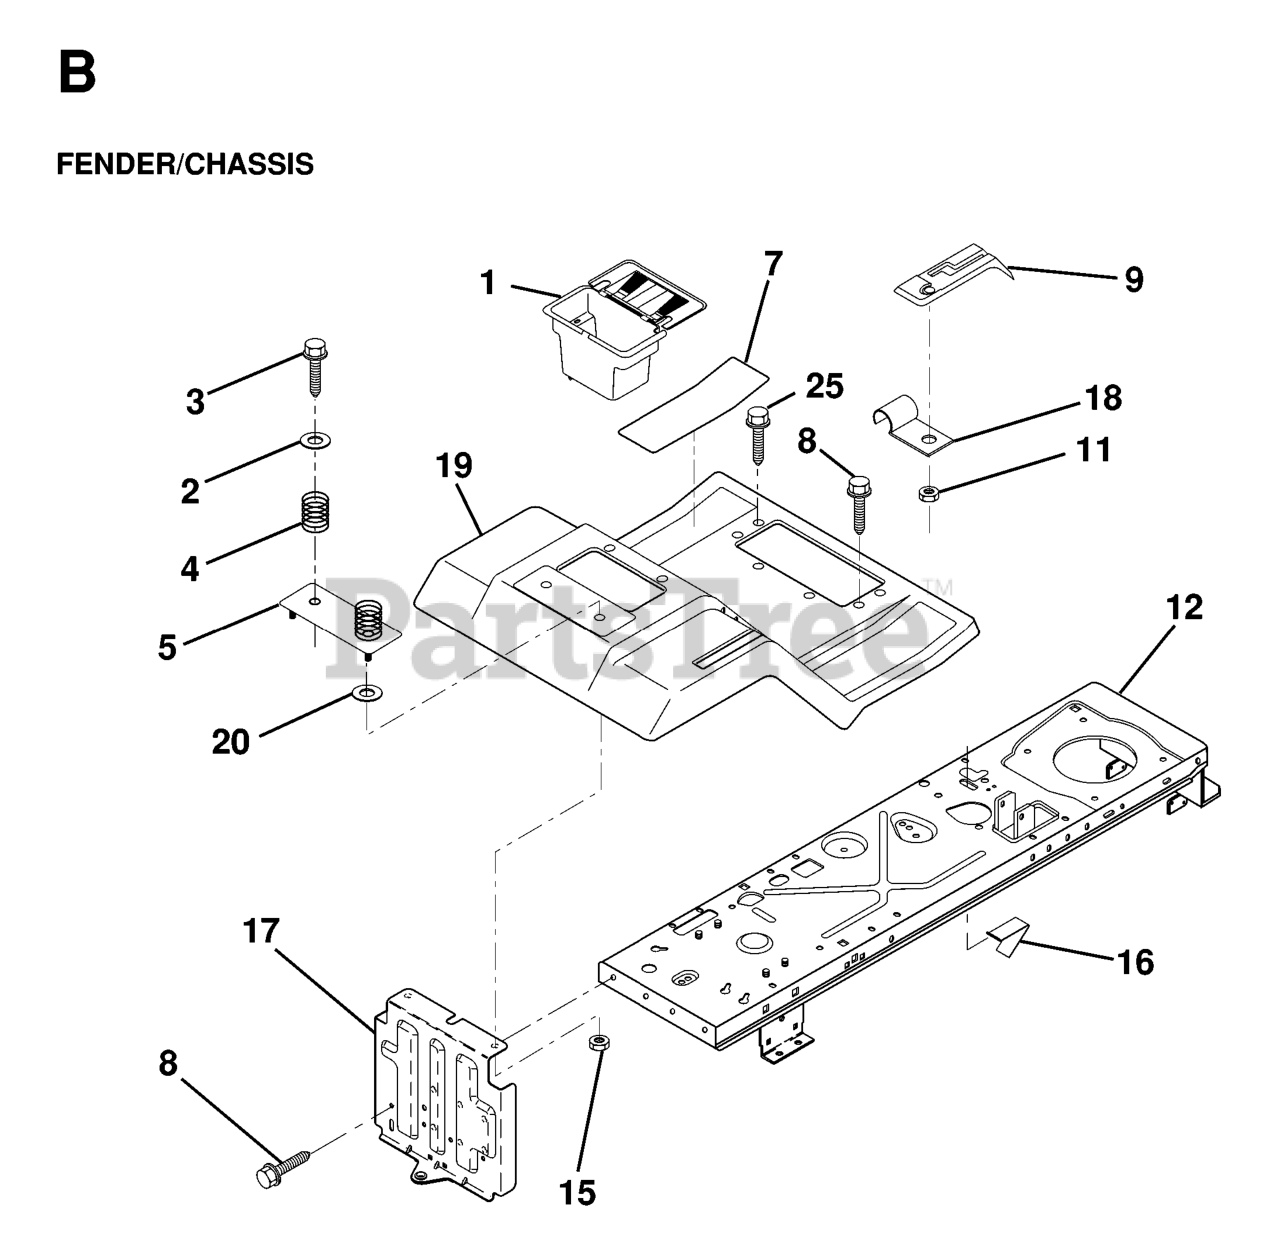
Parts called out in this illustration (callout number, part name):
1	CASE BATTERY MECH HINGE
2	WASHER
3	SCREW
4	SPRING COMPRESSION
5	PLATE ASM BATTERY
7	FOOTREST PAD
8	SCREW.THDROL.5/16-18X3/4.TTY
9	CONSOLE SHIFT CTL
11	NUT.PUSH.3/16
15	Nut, Keps Blk Hex 1/4-20 UNC
16	SWITCH ACTUATOR
18	CLIP,INSULATOR
19	FENDER/FOOTREST
20	WASHER
25	Screw Hex Wsh Thdroll 5/16-18 x 1
